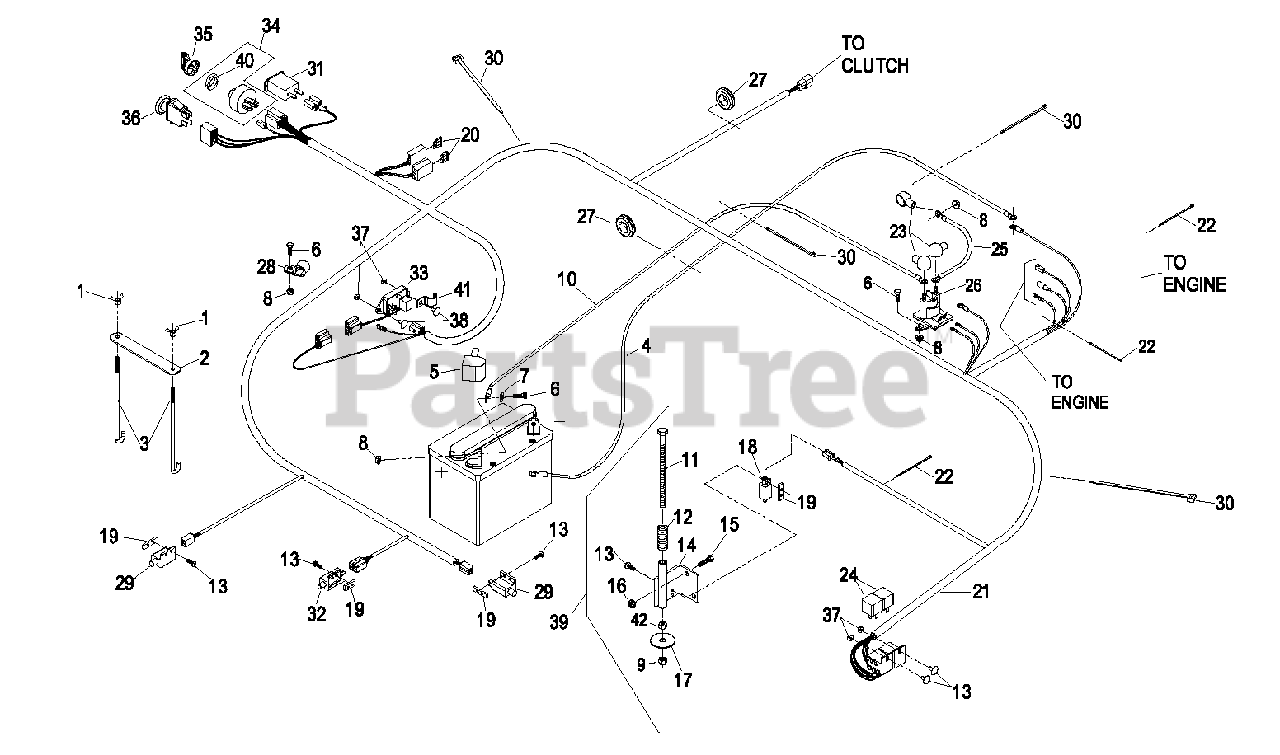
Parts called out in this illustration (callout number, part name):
1	WINGNUT
2	STRAP-HOLDDOWN, BATTERY
3	BOLT-HOLDDOWN
4	CABLE-GROUND, NEGATIVE
6	SCREW-HH
7	WASHER-FLAT
9	NUT-LOCK, NI
11	SCREW-HH
12	SPRING-SWITCH, SEAT
13	SCREW-PPH
14	BRACKET-SWITCH, SEAT
15	SCREW-HH
18	SWITCH-CLOSED, NORMALLY
19	PLATE-TAPPED
20	FUSE-BLADE TYPE, 20 AMP
21	HARNESS,WIRE LHP KA
22	TIE-CABLE
23	INSULATOR-SOLENOID
27	GROMMET
28	CLIP-LOOM
29	SWITCH-OPEN, NORMALLY
30	TIE-PLASTIC
31	METER-HOUR
33	MODULE-DELAY, SEAT
34	ASM,SWITCH W/NUT
35	KEY-IGNITION
35	KEYS-IGNITION (SPARE PAIR
36	SWITCH-PTO
37	NUT-LOCK, NI
38	SCREW-HEAD, TRUSS
39	ASM,SEAT SWITCH ACTUATOR
40	NUT-SWITCH, IGNITION
41	CLIP-HALF, LOOM
42	NUT-HEX
